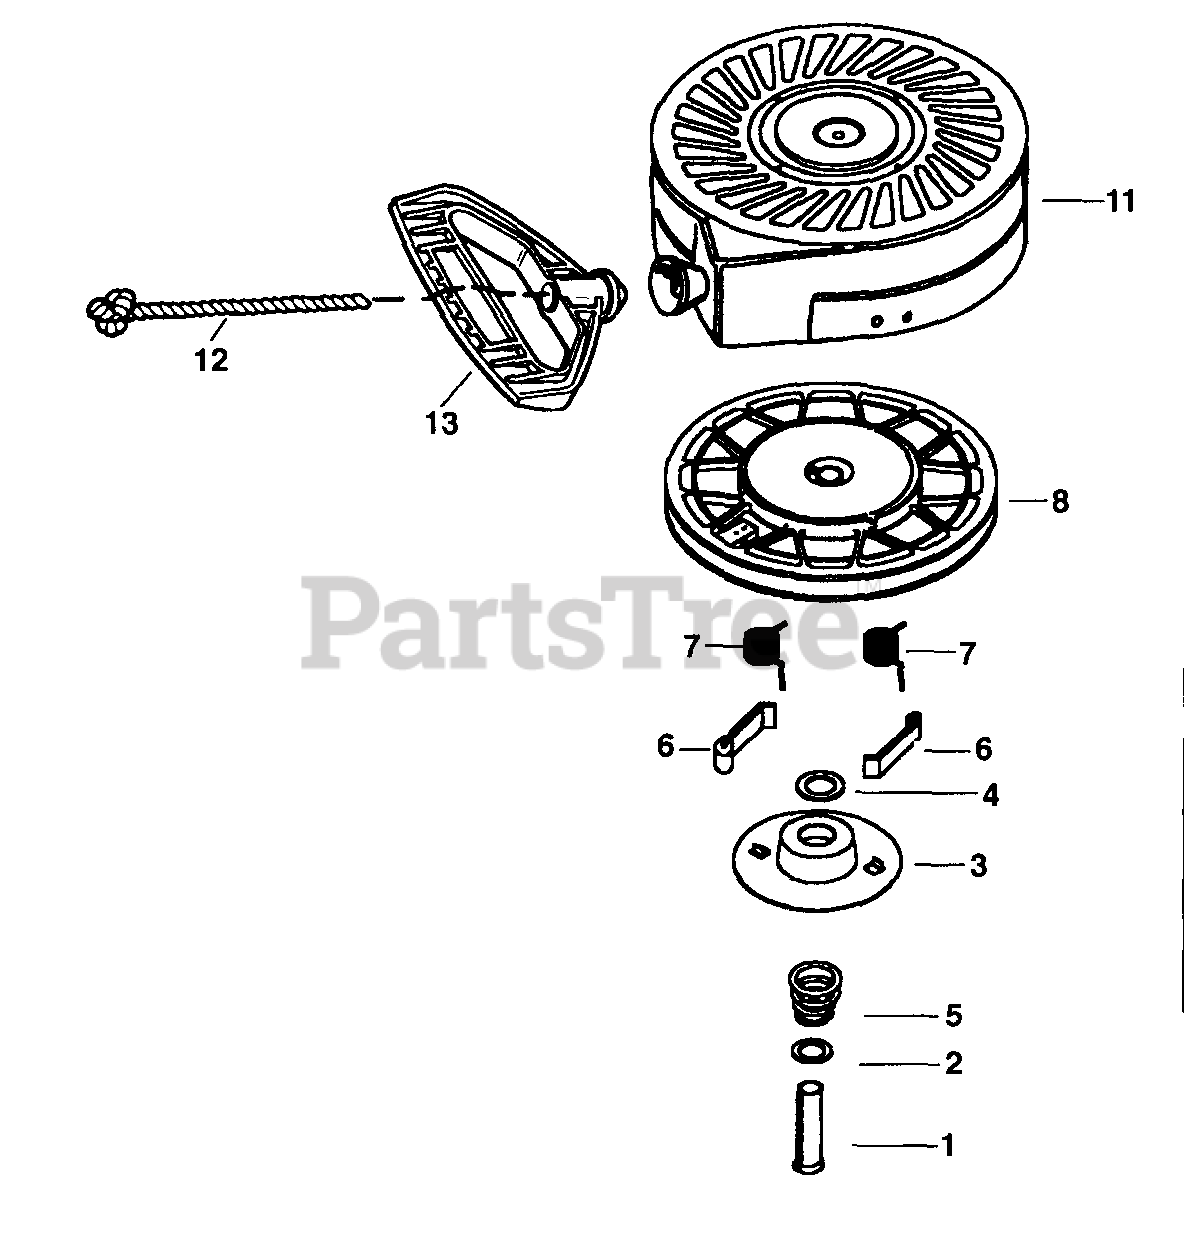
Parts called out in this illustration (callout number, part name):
1	Spring Pin
5	Brake Spring
6	Starter Dog
7	Dog Spring
8	Pulley & Rewind Spring Ass'y.
11	Starter Housing Ass'y.
12	Starter Rope (98" x 9/64" dia.)
13	Mitten GripHandlee
